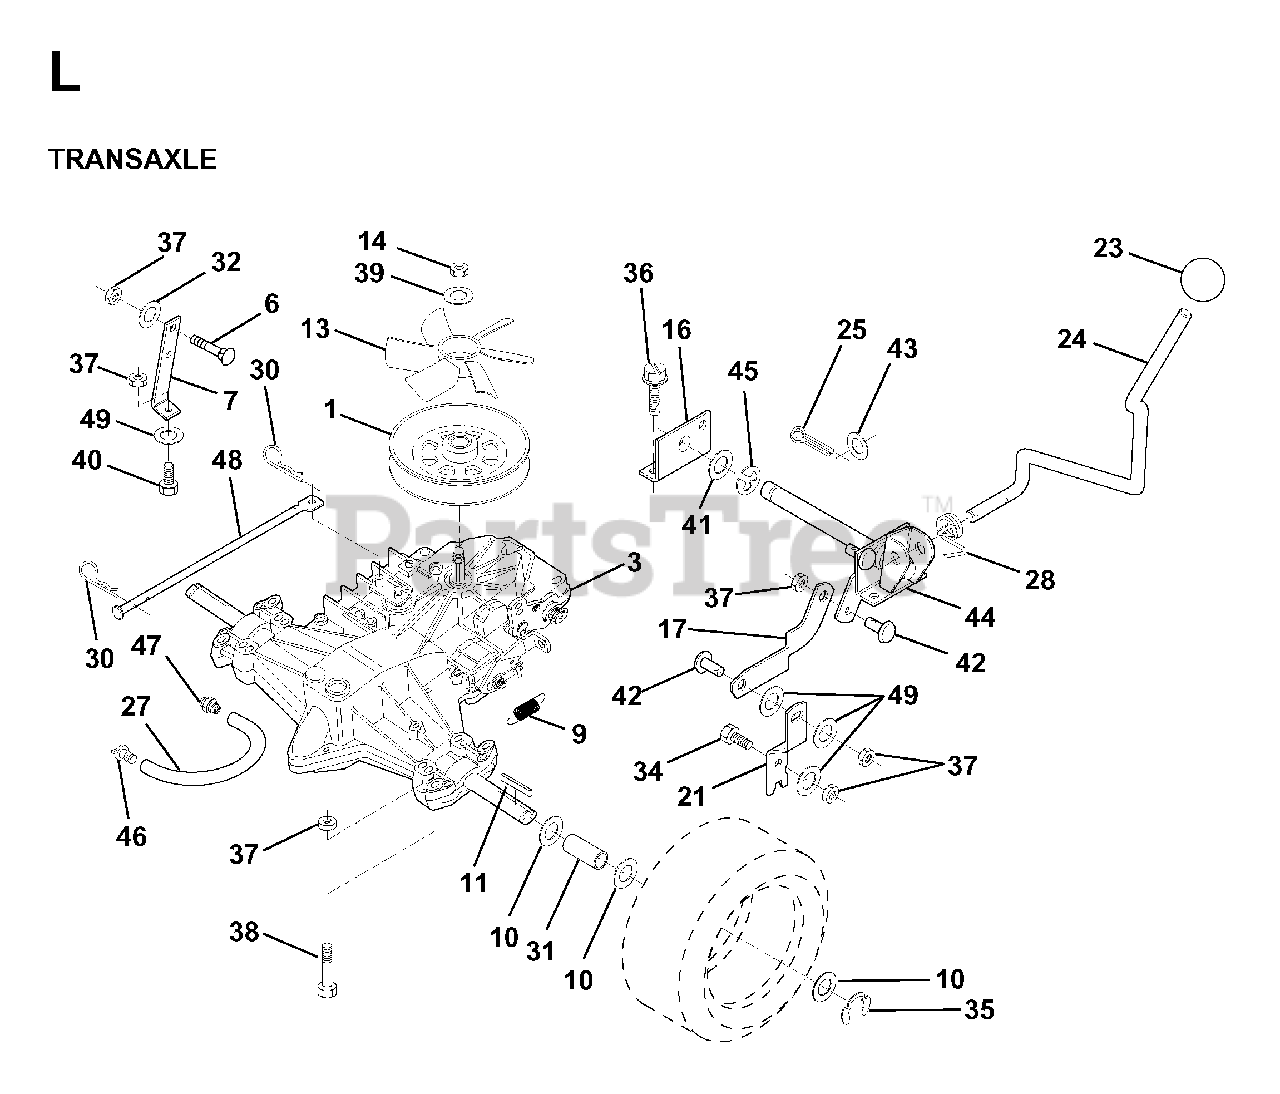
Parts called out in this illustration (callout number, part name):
3	TRANSAXLE HYDRO
6	BOLT
9	SPRING,BRAKE RETURN
11	SQUARE KEY
13	FAN.TRANSMISSION.HYDRO.6"
16	SUPPORT, SHIFT HANDLE
17	LINK, SHIFT
21	LEVER, SHIFT
23	PISTOL KNOB
24	ROD, SHIFTER
25	PIN COTTER
27	FUEL LINE
28	SPRING, TORSION
30	RETAINER M
31	SPACER SPLIT
32	WASHER
34	BOLT RB
35	E-RING LT
36	SCREW
37	NUT.71038.31-18.HEX.NYLOCK
40	BOLT
43	WASHER
44	PIVOT SHAFT
45	RETAINING RING LT
48	ACTUACTOR
49	WASHER M
